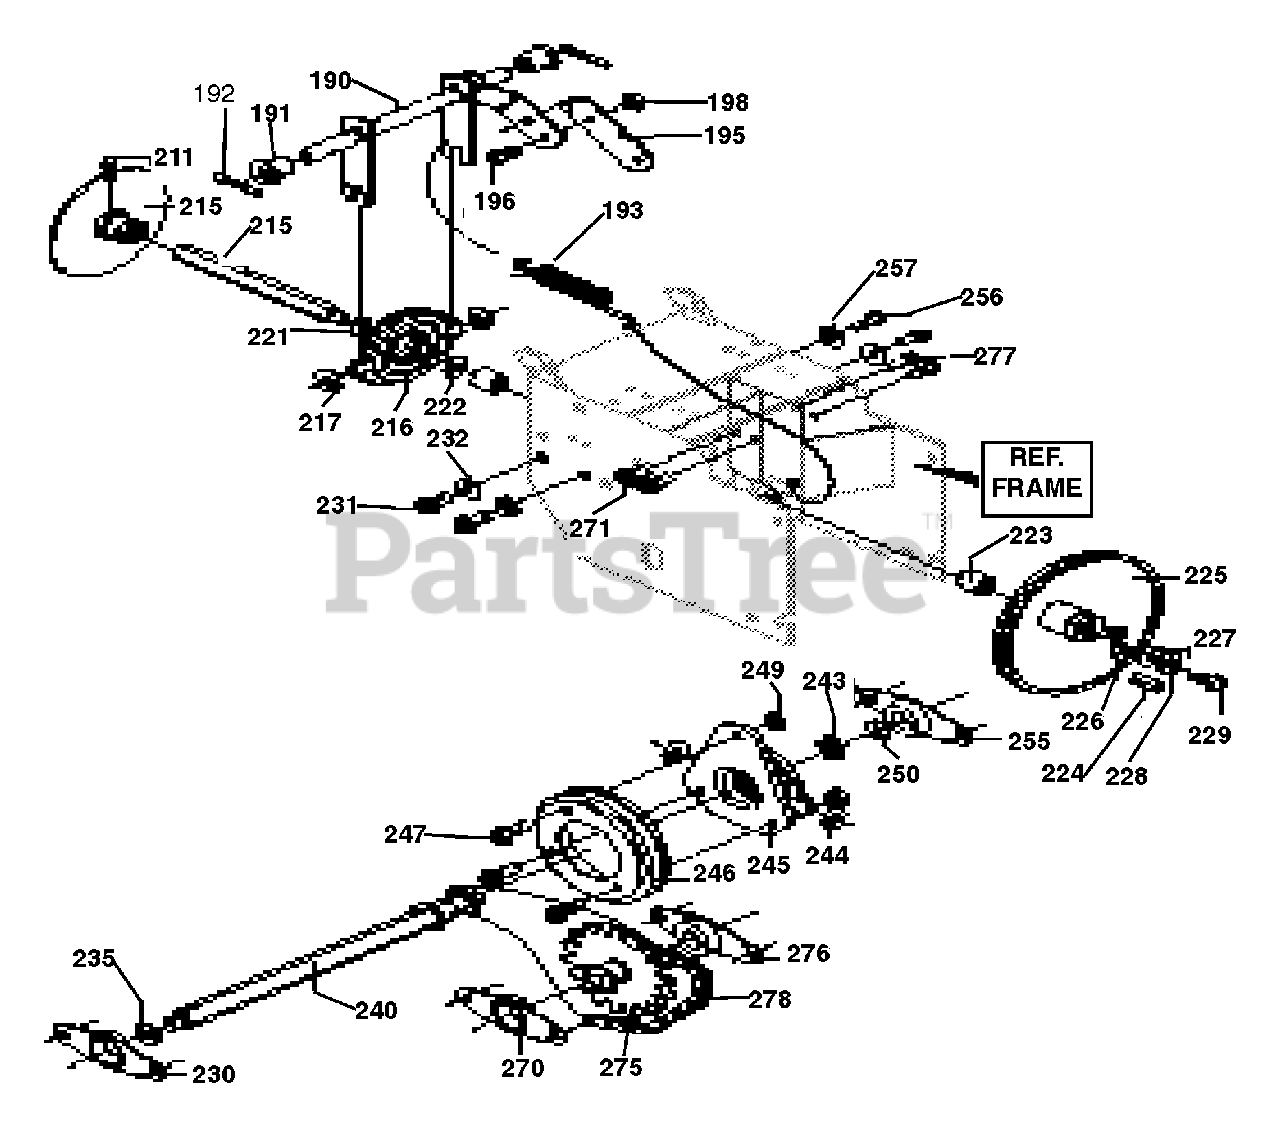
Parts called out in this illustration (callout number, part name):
190	LEVER, ASSY TRCTN
191	BEARING, FLANGE
192	PIN, COTTER
193	SPRING, RETURN
195	LEVER, SPRING
196	SCREW, 1/4-20 X .63
198	NUT, 1/4-20 REGHEX
210	DISC, ASSY
211	ZERK, GREASE
215	SHAFT, HEX TRACTION
216	BEARING, TRUNION
217	FLATWASHER,
221	RING, RETEX
222	FLATWASHER,
223	BEARING, BALL
224	KEY, SQUARE
225	PULLEY, V3L 6.50 X .56
226	WASHER, WAVE
227	FLATWASHER,
228	WASHER, .263 X .49 X .07
229	SCREW, 1/4-20 X .75 HHC
230	BEARING & RETAINER
231	SCREW, 5/16-18 X .50
232	WASHER, .328 X .60 X .09
235	WASHER, .502 X .75 X .0605
240	HEX, ASSY #40-8T
243	RING, RETEX
244	FLATWASHER,
245	BEARING, TRUNION
246	WHEEL, ASSY FRICTION
247	SCREW, 1/4-20 X .63
249	NUT, 1/4-20 HEXKEPS
250	WASHER, .502 X .75 X.0605
255	BEARING & RETAINER
256	SCREW, 5/16-18 X .50
257	WASHER, .328 X .60 X .09
270	BEARING & RETAINER
271	SCREW, 5/16-18 X .50
275	JACK, ASSY #41-36T & 8T
276	BEARING & RETAINER
277	SCREW, 5/16-18 X .50
278	CHAIN, ROLLER #42 X
